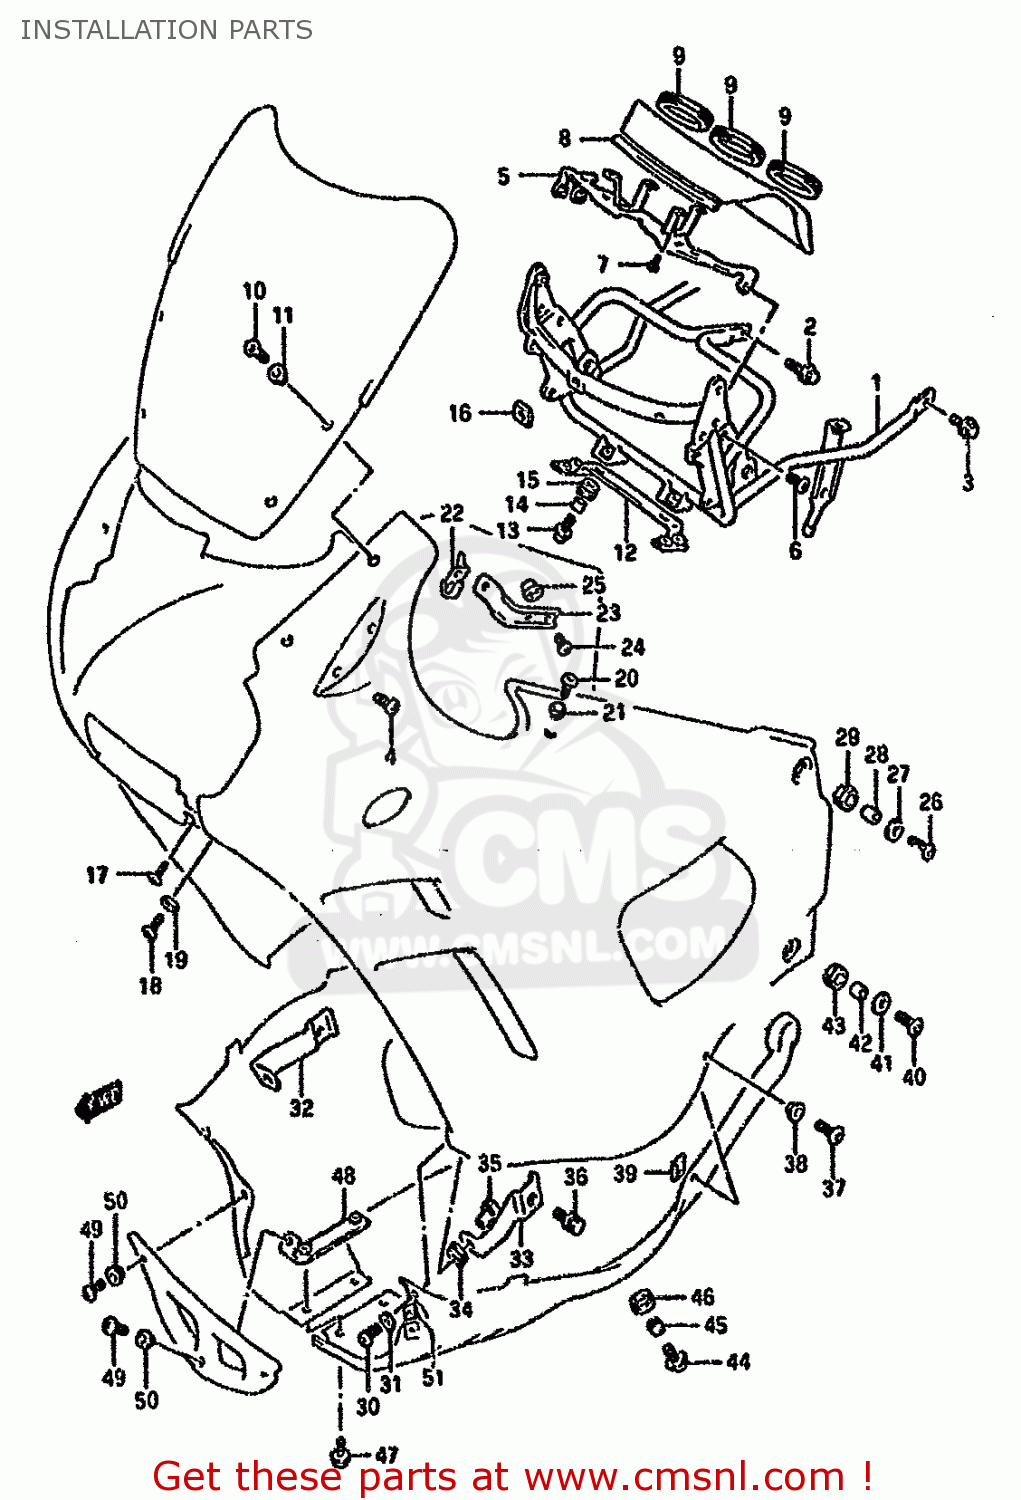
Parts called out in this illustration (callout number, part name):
1	BRACE,COWLING
2	BOLT
3	BOLT
4	SCREW 6X12
5	PLATE,METER FITING
6	SCREW 6X12
7	SCREW 5X8
8	MOLDING,METER COVER
9	CUSHION,METER COVER
10	SCREW
11	WASHER
12	PLATE,COWL CTR PANEL
13	SCREW(6X20)
14	SPACER (6,8X10X9.4)
15	CUSHION
16	CUSHION,SCREEN
17	SCREW
18	SCREW(6X25)
19	WASHER
20	SCREW(6X16)
21	WASHER(6.3X16X1.5)
22	BRACKET,COWLING UPR,R
23	BRACKET,COWLING UPR,L
24	SCREW
25	NUT,COWLING SIDE BRKT
26	SCREW(6X25)
27	WASHER
28	SPACER (6.1X9X9)
29	CUSHION
30	SCREW(6X30)
31	WASHER
32	BRACKET,COWLING LWR,R
33	BRACKET,COWLING LWR,L
34	CUSHION
35	NUT,COWLING,FR
36	BOLT
37	SCREW(5X14)
38	WASHER(5.2X14X1.5)
39	NUT,HEADLAMP HOUSING,UPPER
40	SCREW(6X25)
41	WASHER
42	SPACER(6.1X9X12.3)
43	CUSHION
44	SCREW(6X20)
45	SPACER (6.1X9X9)
46	CUSHION
47	SCREW
48	BRACKET,FR UNDER COWL
49	SCREW
50	WASHER(5.2X14X1.5)
51	NUT,HEADLAMP HOUSING,UPPER
